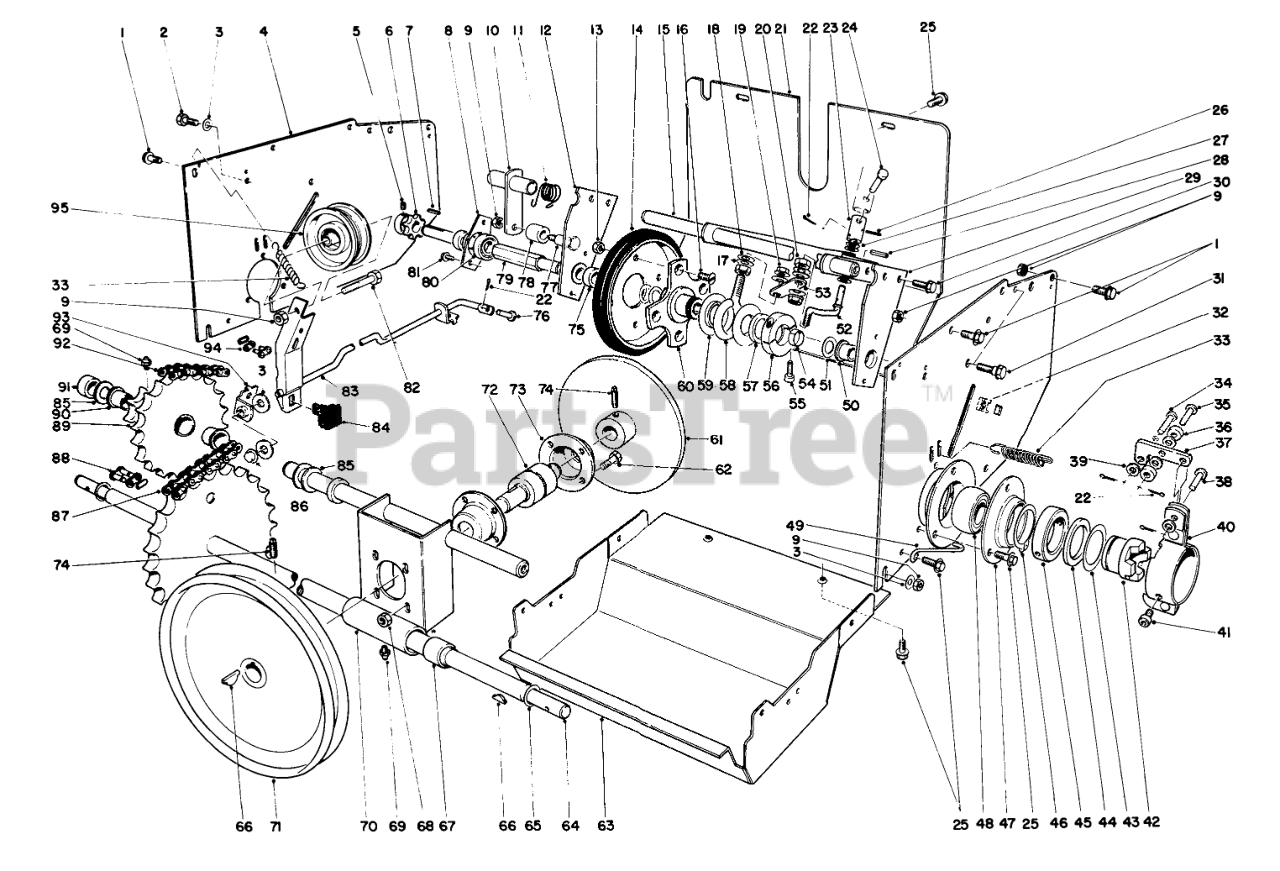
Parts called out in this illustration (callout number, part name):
1	SCREW-HH
2	SCREW-HHFTF
3	WASHER-FLAT
4	Side Plate Drive
5	SCREW-HSH
6	SPROCKET
8	BEARING CUP
9	NUT-HEX
10	CHAIN TENSION ARM WA
11	TORSION SPRING
12	HEX SHAFT MOUNT R
13	Nut
14	FRICTION WHEEL
15	Bracket Dead Shaft
16	5/16-18X5/8 FLT HD MS
17	WASHER-FLAT
18	WASHER-SPRING
19	NUT-LOCK, FLANGE
20	Nut
21	REAR COVER R
22	PIN-COTTER
23	U JOINT TUBE
24	CLEVIS PIN
25	SCREW-HWH
26	PIN-SPRING
27	Clevis Pin
28	PIN-ROLL
29	Hex Shaft Mounting (Incl. Ref. #50)
30	SCREW-HWHTF
31	SHOULDER SCREW
32	RETAINER NUT
33	EXTENSION SPRING
34	PIN-CLEVIS
35	PIN-CLEVIS
36	CLUTCH ROLLER
37	CLUTCH CAM ARM
38	PIN-CLEVIS
39	WASHER-FLAT
40	CLUTCH MT BRKT ASM
41	SCREW-HSH
42	WHEEL CLUTCH
43	THRUST WASHER
44	THRUST BEARING
45	CLUTCH MOUNT COLLAR
46	RING-RETAINING, EXTERNAL
47	BEARING FLANGE
48	BEARING
49	CLUTCH RETAINER
50	BUSHING
51	WASHER-FLAT
52	CONNECTION ROD
53	SHIFT ROD PIVOT
54	SPLIT SPACER
55	SCREW-HSH
56	ColIar
57	WASHER-THRUST
58	SLIDER RING COLLAR
59	SLIDER RING
60	TRACTION DISC HUB
61	FRICTION PLATE O
62	SCREW-HH
63	LOWER SHIELD R
64	AXLE SHAFT WA
65	WASHER
66	KEY-WOODRUFF
67	BUSHING
68	NUT-KEPS
69	FITTING-GREASE
70	Bulkhead (Incl. Ref. #67)
71	Pulley
72	BEARING-FRICTION PLATE
73	HOUSING BEARING
74	SCREW-SET, SQH
75	SPACER
76	PIN-CLEVIS
77	SHOULDER BOLT
78	CHAIN TENSION ROLLER
79	FRICTION WHEEL SHAFT
80	BEARING
81	SCREW
82	SCREW-HH
83	Auger Brake Assembly (Incl. Ref. #84)
84	Brake Pad
85	WASHER-THRUST
86	PUSH NUT
87	ROLLER CHAIN
88	LINK-CHAIN
89	Sprocket (Incl. Ref. #69 & 90)
90	3/4ID X 3/4LG BSHG
91	SPACER-IDLER
92	1/4 X 42 CHAIN W/LINK
93	Bracket-Clutch
94	LINK-CONNECTING
95	PULLEY-IDLER
